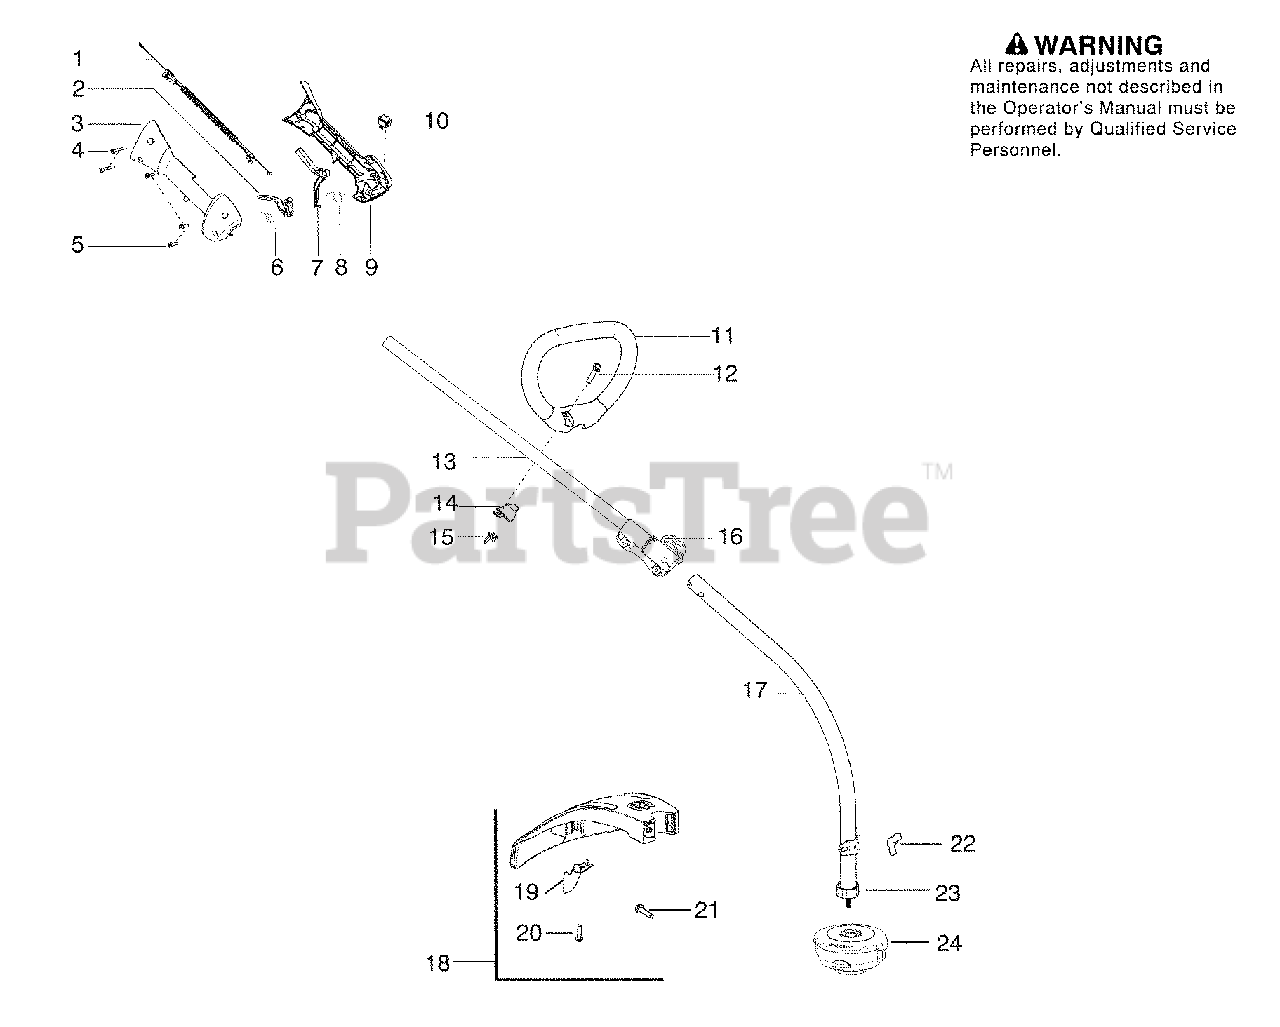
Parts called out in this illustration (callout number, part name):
1	Assy-Cable/Wire Harness
3	Housing-Throttle
6	Spring-Trigger
7	Lockout-Throttle
8	Spring-Lockout
9	Housing-Throttle
10	Kit-Switch
11	Handle - Assist
13	Kit-Driveshaft Upper
14	Clamp - Assist Handle
15	Wingnut
17	Kit-Lower Shaft
18	Kit-Shield
19	Limiter - Line
22	Wingnut
23	Dust Cup
24	Head - Cutting
